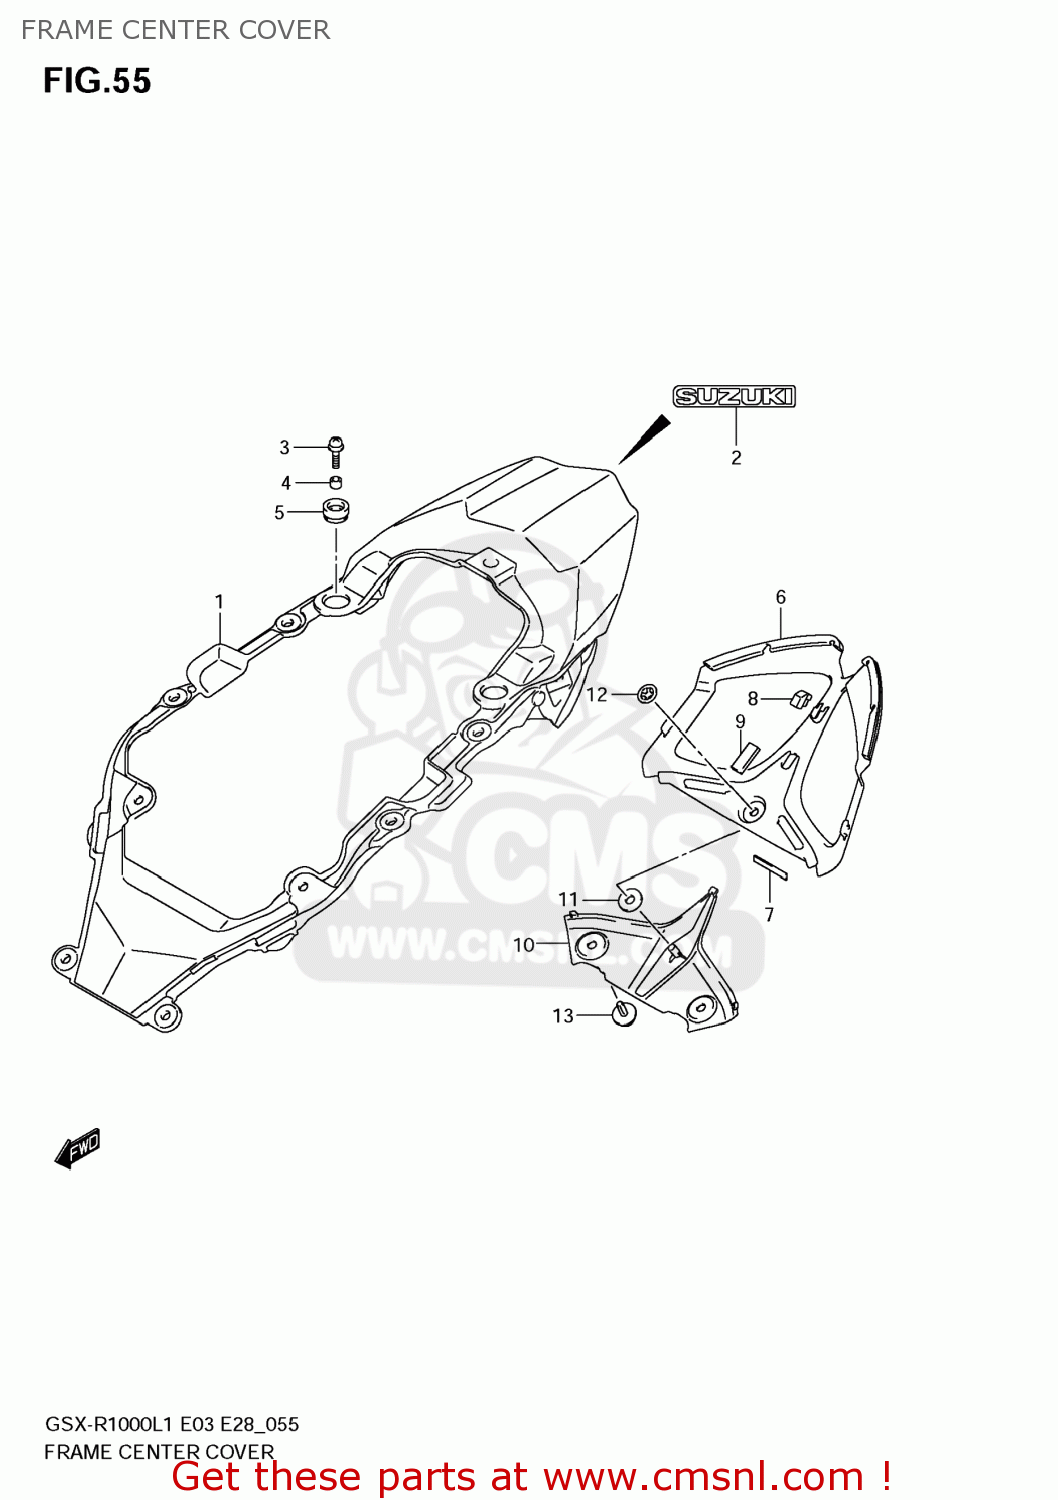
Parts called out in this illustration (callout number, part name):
1	COVER ASSY,FRAME CTR
2	EMBLEM,SUZUKI
3	SCREW(6X16)
4	SPACER(6.5X10X7)
5	CUSHION,FRAME COVER RR
6	COVER,FRAME RR CTR
7	CUSHION,FRAME COVER RR CTR
8	CUSHION,FRAME COVER RR CTR
9	CUSHION,CTR PANEL UPR
10	COVER,FRAME RR CTR LWR
11	CUSHION
12	NUT
13	CLIP
